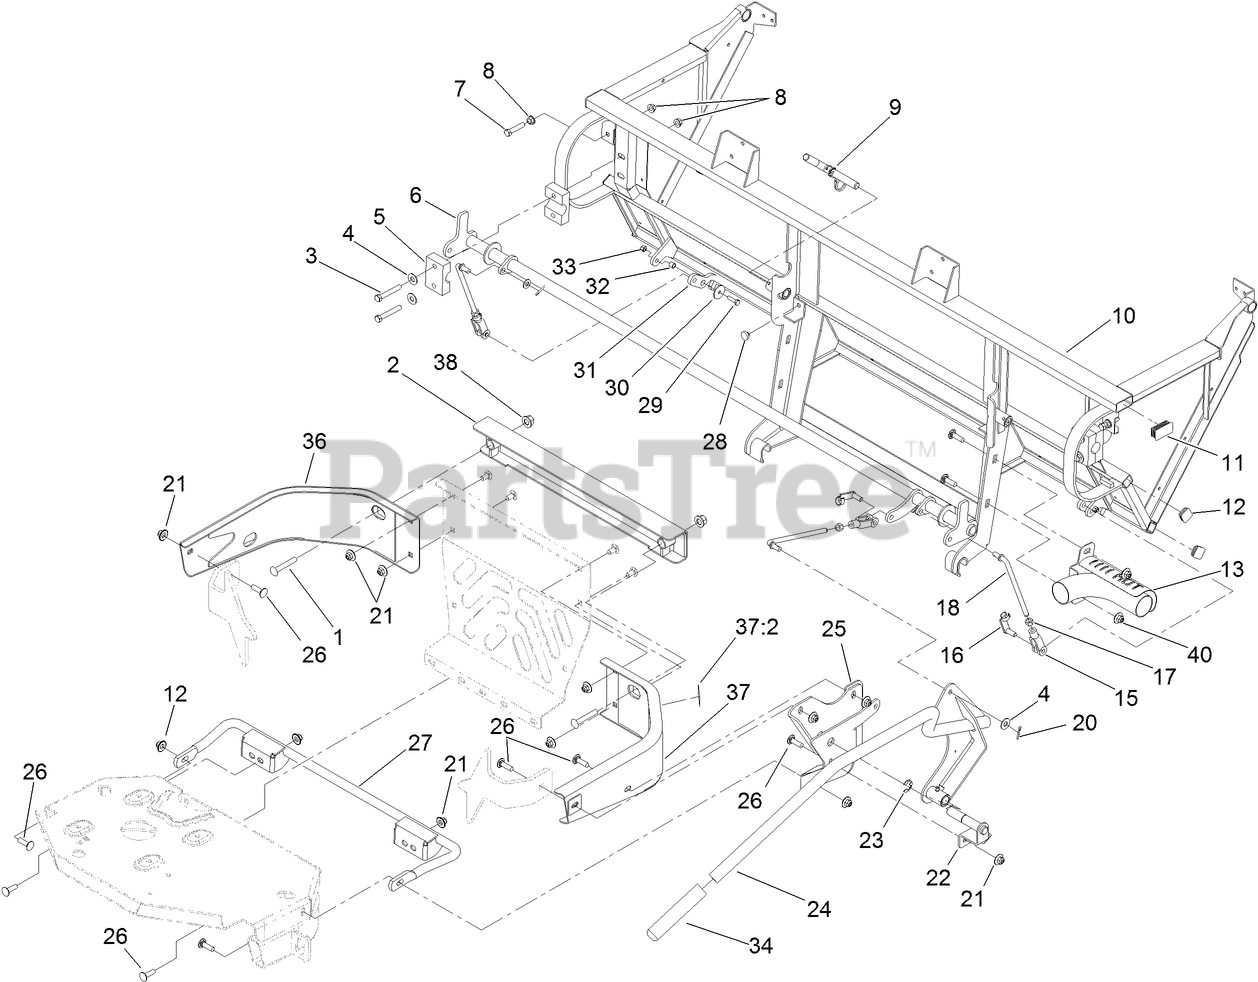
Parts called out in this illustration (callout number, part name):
1	SCREW-CARR
2	MOUNT-BAGGER, UPPER
3	SCREW-HH
4	WASHER-FLAT
5	HALF-BLOCK, BEARING
6	LINK-INTERMEDIATE
7	SCREW-HH
8	NUT-HHF, WHIZ
9	PIN-MOUNT, BAGGER
13	DIVERTER-EXHAUST
15	YOKE-LINKAGE, BRAKE
16	Pin-Spring, Clevis
17	NUT-HEX
18	LINK-HANDLE
20	PIN-COTTER
21	NUT-FLANGE, NI
22	PIN-HANDLE
23	E-RING
24	BAGGER HANDLE ASM
25	MOUNT-PIVOT
26	SCREW-CARR
27	MOUNT-BAGGER, LOWER
28	BUMPER
29	SCREW-HH
30	WASHER-FLAT
32	SPACER
33	NUT-LOCK, NI
34	HANDLE-GRIP
36	BUMPER-RH
37	LH BUMPER ASM
37:2	DECAL-CAUTION
38	NUT-LOCK
40	NUT-HF, NI
